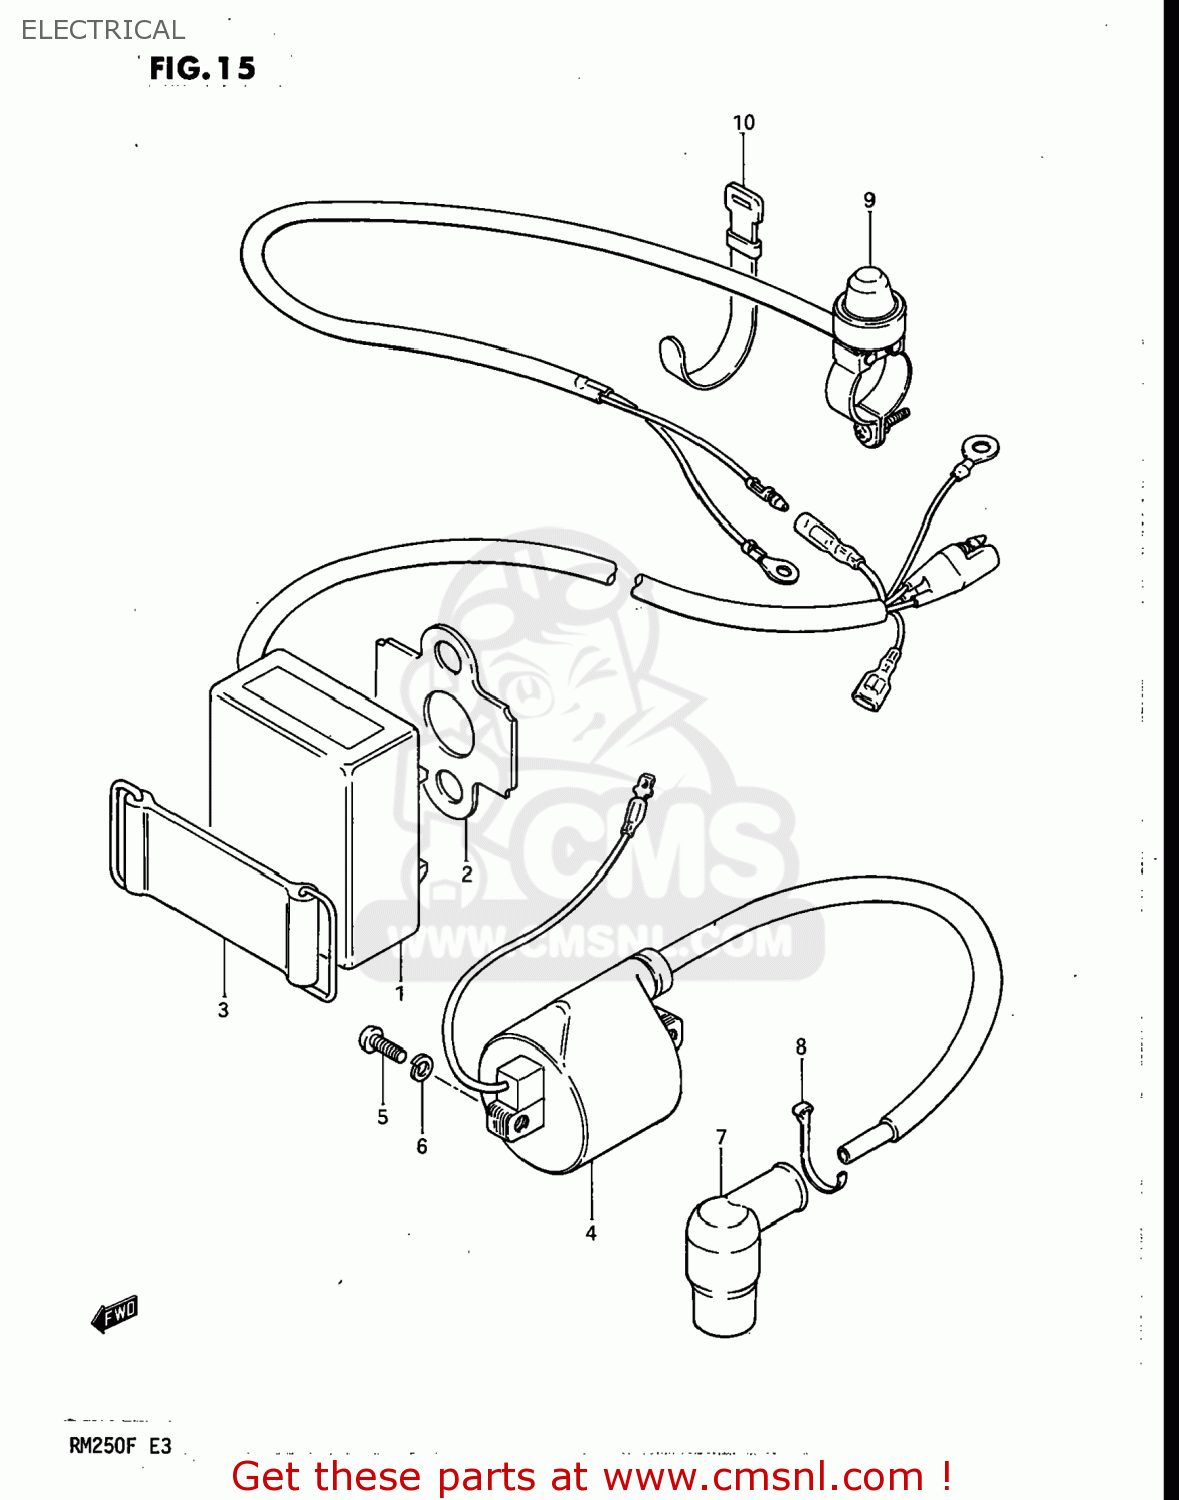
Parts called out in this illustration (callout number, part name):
1	CDI UNIT
2	PROTECTOR,CDI UNIT
3	BAND
4	COIL ASSEMBLY,IGNITION
5	SCREW
6	LOCK WASHER
7	CAP,SPARK PLUG
8	CLAMP
9	SWITCH ASSEMBLY
10	CLAMP(L:120)
